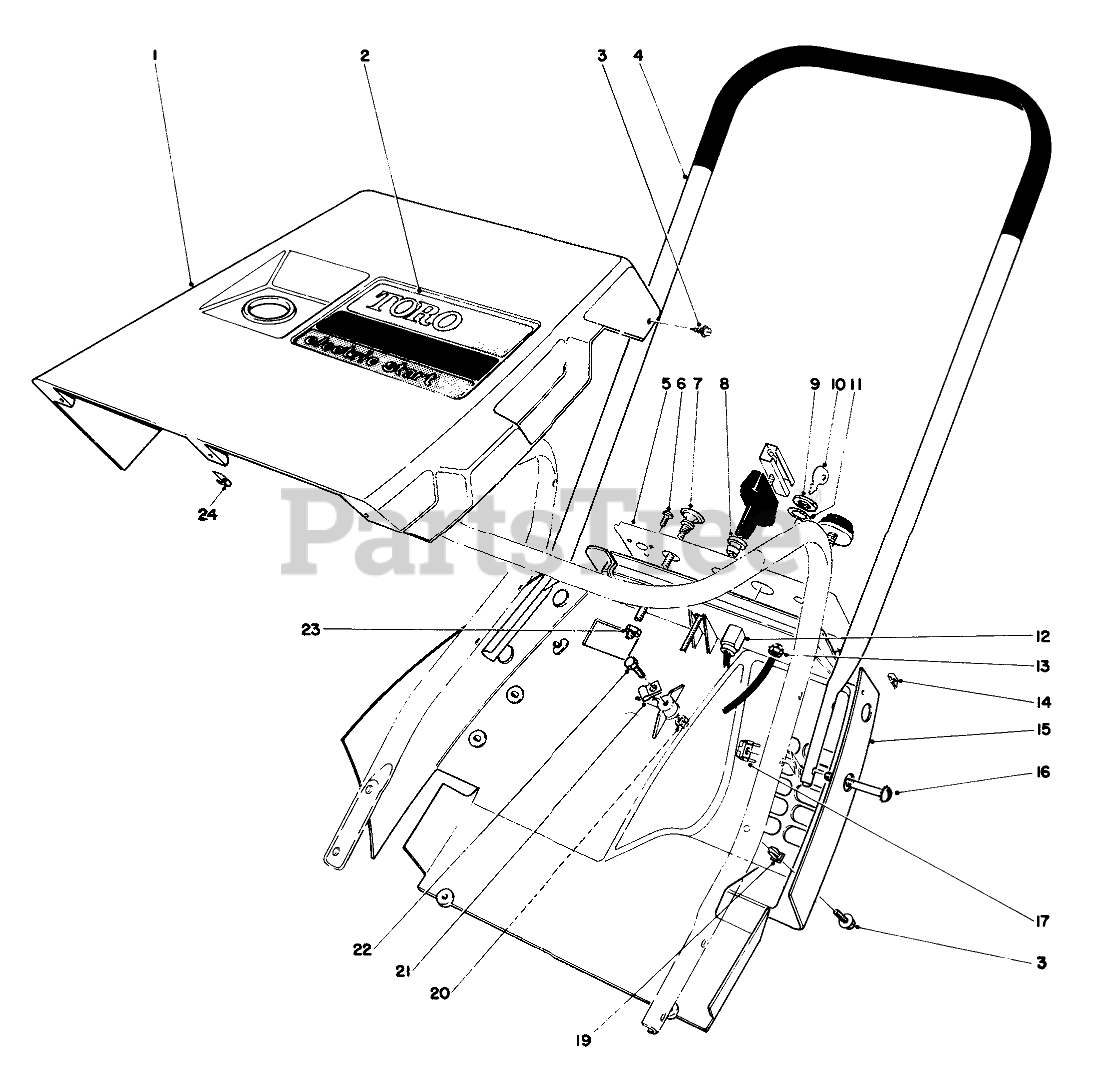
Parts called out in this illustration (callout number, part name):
1	Upper Shroud
2	Decal-Toro
3	SCREW-HWHTF
4	Upper Handle
5	Decal-Control Panel
6	SCREW-PLASTITE
7	Choke Cable
8	GUIDE-ROPE, STARTER
9	NUT-HH
10	Key
11	WASHER-TOOTH, INTERNAL
12	SWITCH-ON / OFF
13	NUT-KEPS
14	NUT-TYPE J
15	LOWER SHROUD
16	Sems Mach. Screw
17	TINNERMAN NUT
19	Push Nut
20	NUT-LOCK, NI
21	3/16 SUPPORT
22	SCREW-HWH
23	PAL NUT/CHOKE CNTRL
